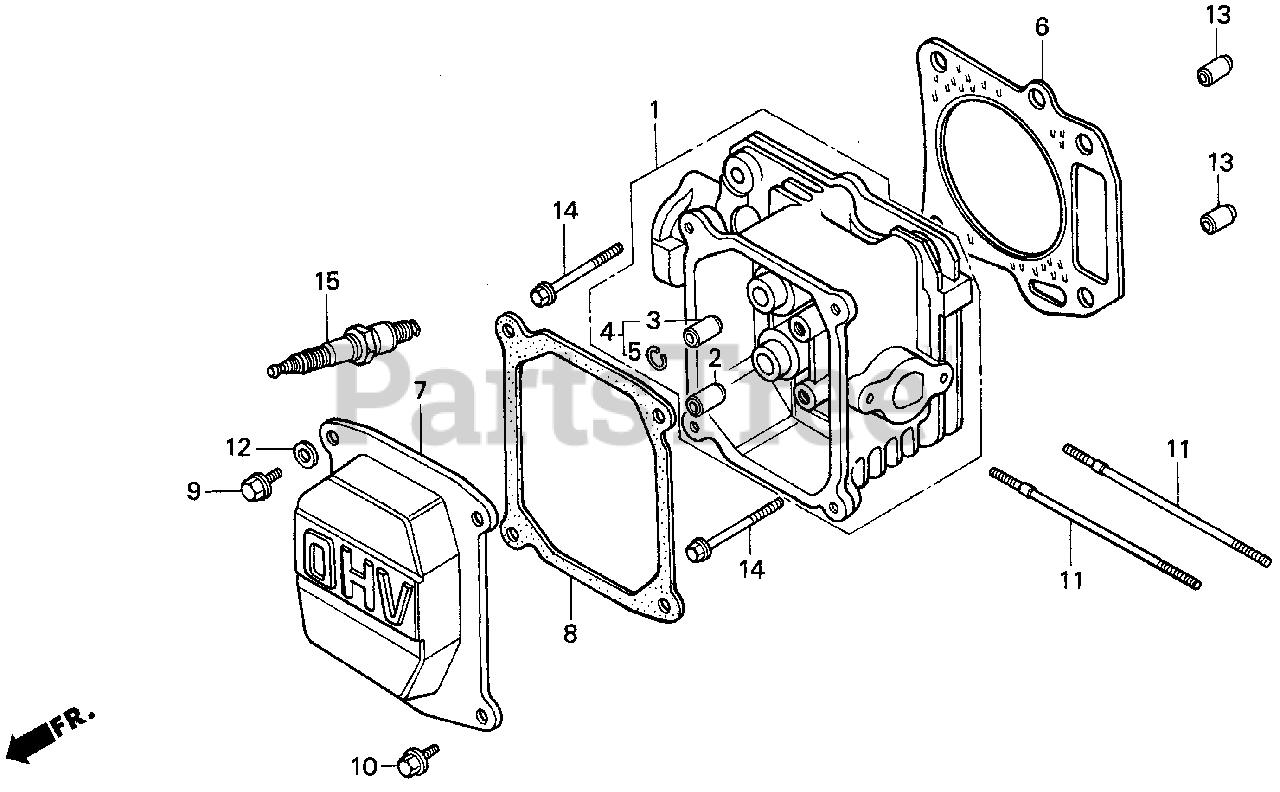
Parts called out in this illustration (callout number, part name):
1	CYLINDER HEAD
1	CYLINDER HEAD (USA)
2	GUIDE, VALVE (OS)
4	GUIDE, EX. VALVE (OS)
5	CLIP, VALVE GUIDE
6	GASKET, CYLINDER HEAD
7	COVER, HEAD
8	GASKET, CYLINDER HEAD COVER
8	GASKET, CYLINDER HEAD COVER (NOT AVAILABLE)
9	BOLT, FLANGE (6X13)
10	BOLT, FLANGE (6X14)
11	BOLT, STUD (6X97)
12	WASHER (6X17)
13	PIN A, DOWEL (10X16)
14	BOLT, FLANGE (8X50)
15	SPARK PLUG (BPR4ES) (NGK)
15	SPARK PLUG (W14EPR-U) (DENSO)
15	SPARK PLUG (BPR5ES) (NGK)
15	SPARK PLUG (W16EPR-U) (DENSO)
15	SPARK PLUG (BPR6ES) (NGK)
15	SPARK PLUG (W20EPR-U) (DENSO)
